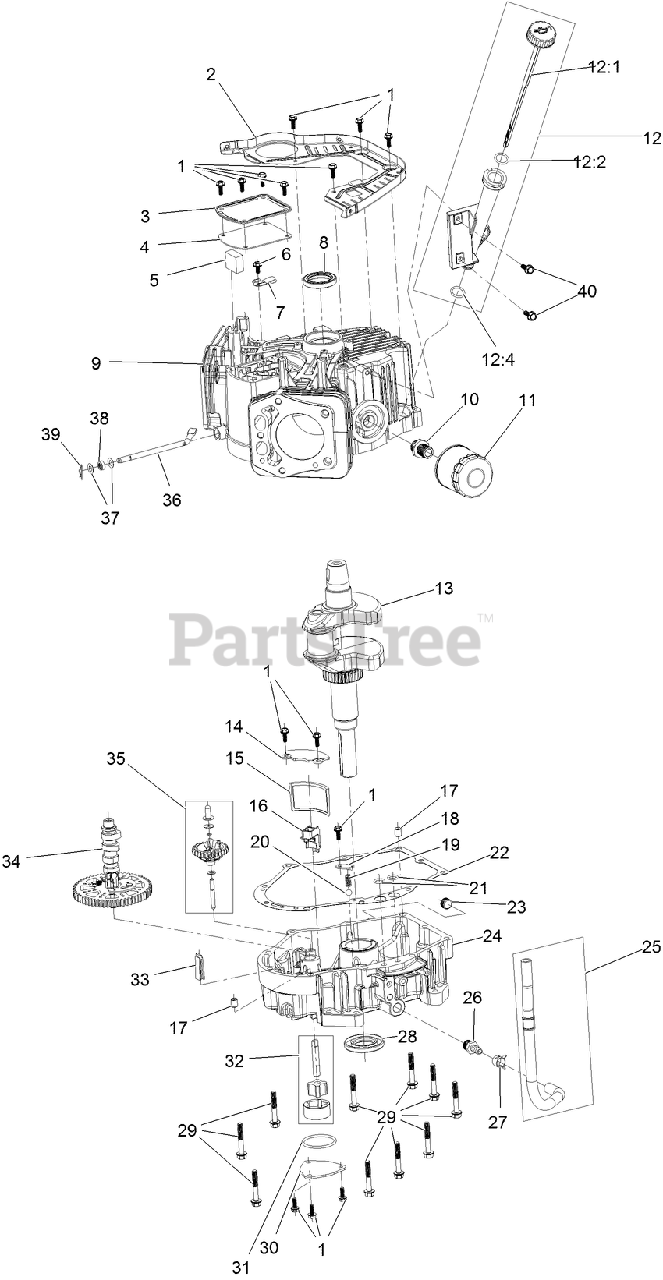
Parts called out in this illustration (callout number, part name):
1	SCREW-HHF
2	BAFFLE
3	COVER-BREATHER
4	GASKET-BREATHER
5	FILTER-BREATHER
6	SCREW-HHF
7	VALVE-BREATHER
8	SEAL-OIL
9	CRANKCASE
12	OIL TUBE ASM
12:1	DIPSTICK
12:2	O-RING
12:4	O-RING
13	CRANKSHAFT
14	COVER-SCREEN, OIL
15	SCREEN-OIL
16	RETAINER-SCREEN
17	PIN-DOWEL
18	PLATE-RETAINER
19	SPRING
20	VALVE-BALL
21	O-RING
22	GASKET-COVER, CRANKCASE
23	PLUG-DRAIN
24	COVER-CRANKCASE
25	OIL DRAIN HOSE ASM
26	FITTING-HOSE
27	CLAMP-HOSE
29	SCREW-HHF
30	COVER-OIL PUMP
31	O-RING
32	OIL PUMP ASM
33	DEFLECTOR-OIL, RUBBER
36	SHAFT-GOVERNOR
37	WASHER-PLAIN
38	SEAL-OIL
39	PIN-HAIR
40	SCREW-HHF
